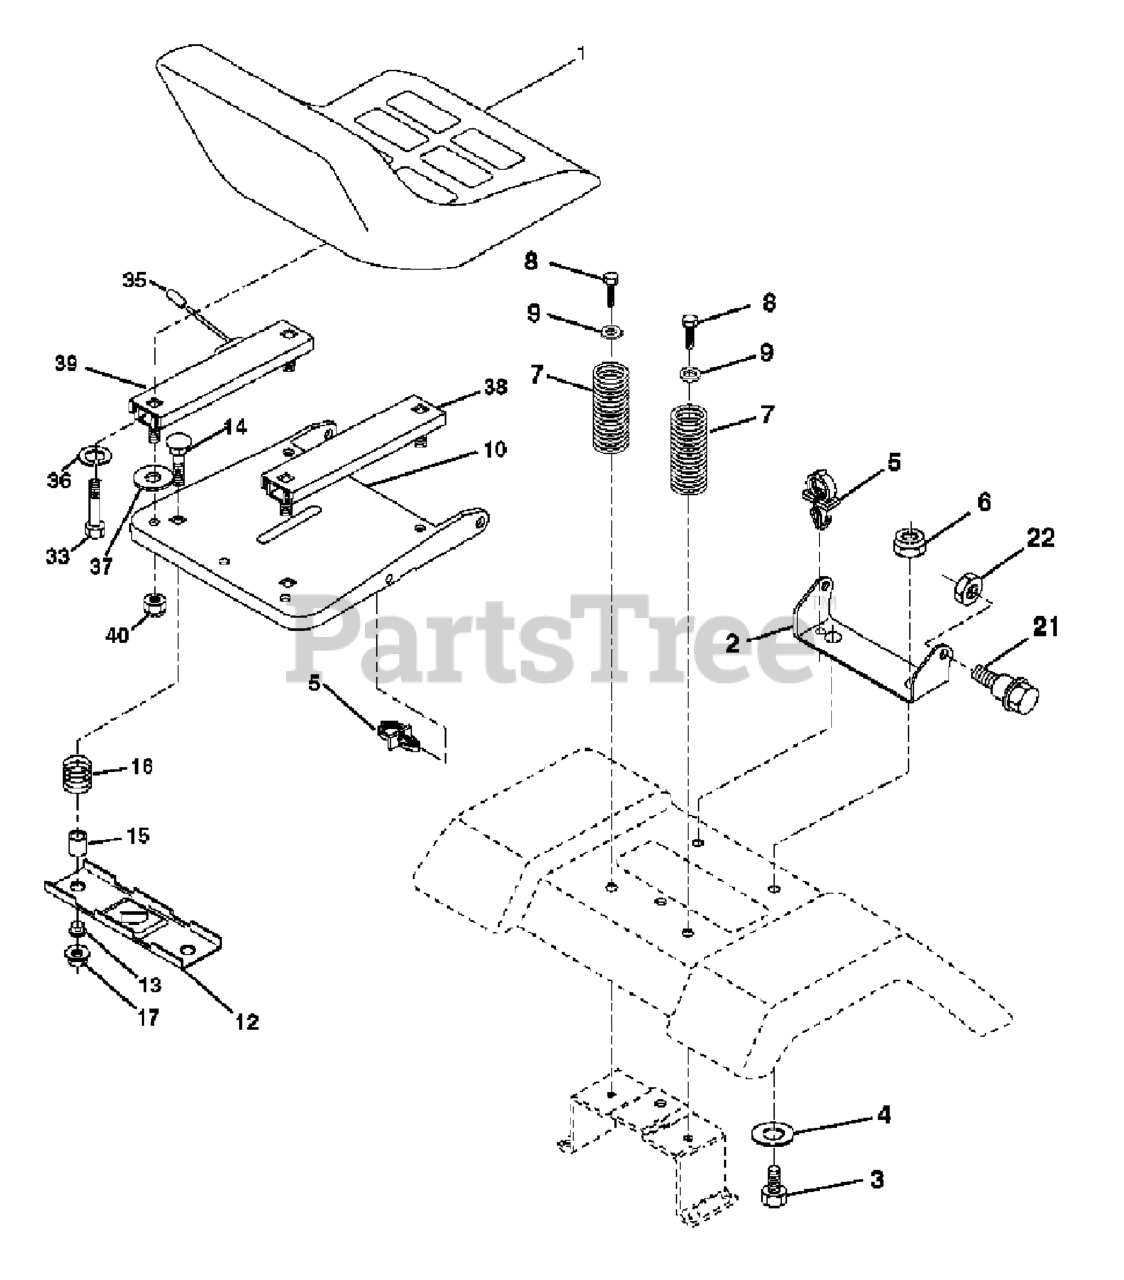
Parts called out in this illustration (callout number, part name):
1	SEAT
2	SEAT PIVOT BRKT
3	BOLT, HEX 3/8-16X1
6	NUT
7	SPRING COMPRESSION
8	SCREW 3/8-16X1
9	WASHER
10	PAN SEAT
12	BRKT SWITCH
14	BOLT.ROUND.HEAD.SQUARE.NECK
15	SPACER SPLIT
16	SPRING COMPRESSED
17	NUT T
21	BOLT.SHOULDER.5/16-18
22	NUT.71038.31-18.HEX.NYLOCK
33	BOLT.FIN.HEX.5/16-18X3/4
35	CAP.VINYL.YELLOW.BUBBLE ASM
37	WASHER T
38	TRACK SLIDE, SEAT(R)
39	TRACK SLIDE, SEAT(L)
40	LOCKNUT
